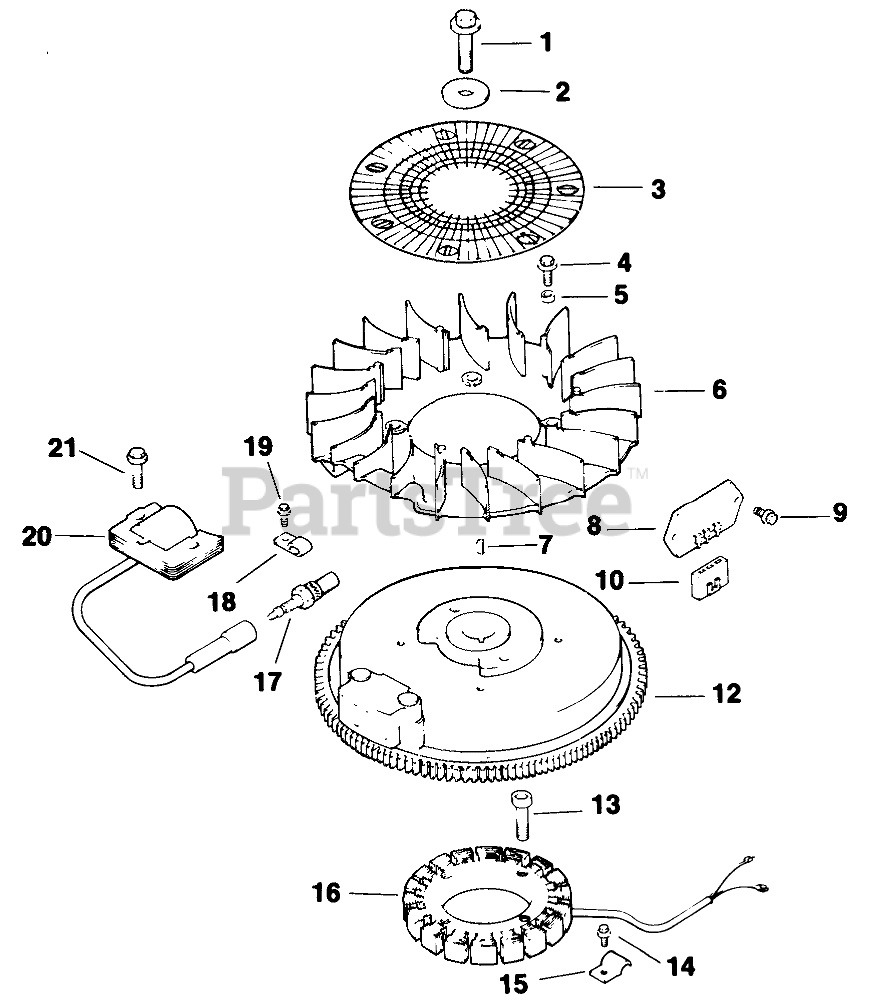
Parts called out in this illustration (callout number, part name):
1	Screw-Flywheel
3	Screen-Grass
4	Screw-Fan
5	Spacer-Fan
6	Fan
7	Key
8	Rectifier-Unregulator
9	Screw-Regulator
10	Connector
12	Flywheel
13	Screw-Stator
15	Clip
16	Stator 15 amp.
17	Spark Plug
18	Clip
20	Module-Ignition
21	Screw
